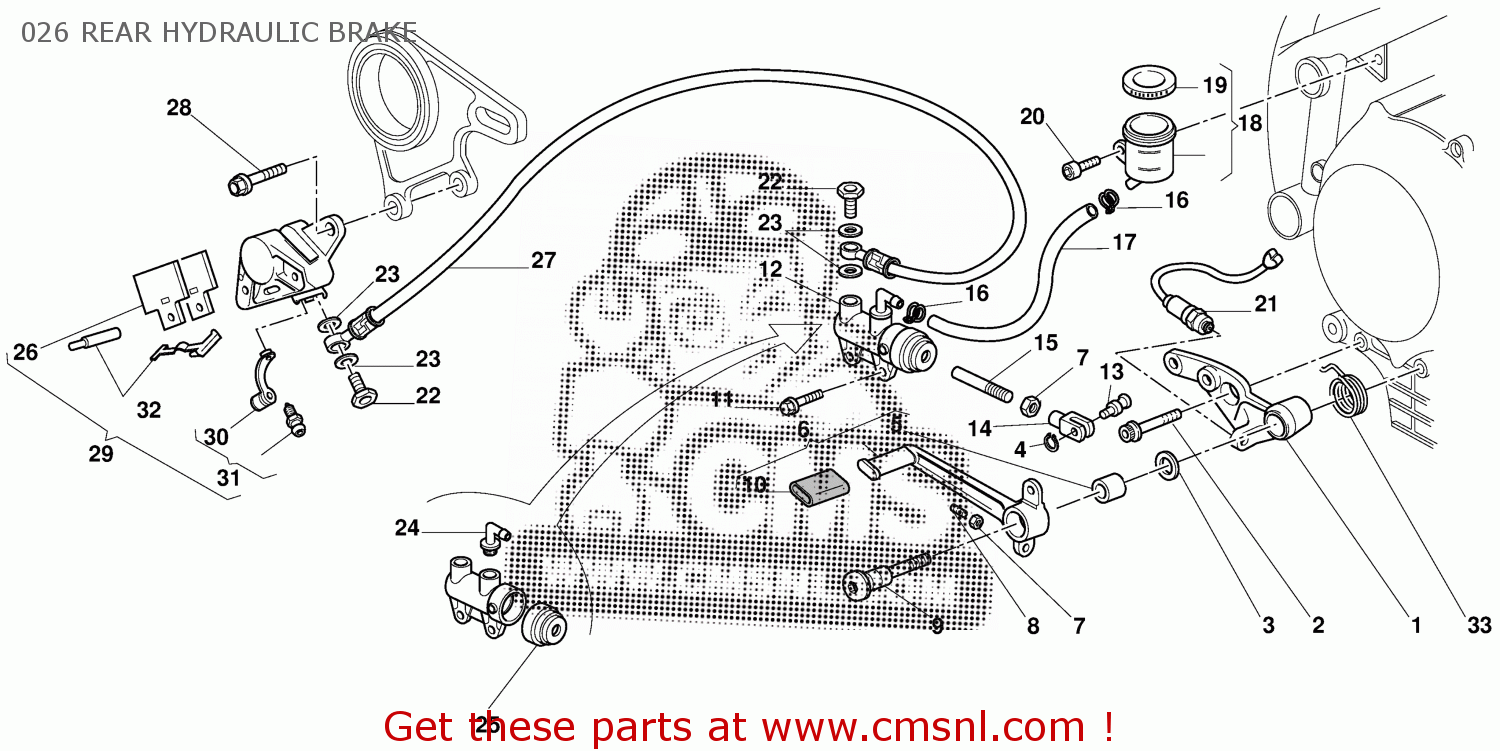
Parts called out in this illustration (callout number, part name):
1	BRACKET, REAR MASTER CYLINDER
2	SCREW TCEIF M10X1.5X25
3	WASHER 10.2X20X1
4	CIRCLIP
5	BUSH
6	PEDAL, BRAKE
7	NUT
8	THREADED DOWEL
9	PIN PEDAL
10	COVER PEDAL
11	BOLT 6X16
12	REAR BRAKE PUMP
13	PIN
14	YOKE
15	BRAKE CONTROL ROD
16	CLAMP
17	HOSE, OIL
18	RESERVOIR, BRAKE FLUID
19	CAP BRAKE FLUID TANK
20	BOLT.HEXAGON SOCKET HEAD M6X10
21	SWITCH, REAR BRAKE
22	SCREW, SPECIAL
23	COPPER GASKET 11.9X8.2X2
24	JOINT, HOSE
25	DUST COVER
26	REAR BRAKE PADS SET (NAS)
27	REAR BRAKE HOSE
28	SCREW
29	REAR BRAKE CALIPER
30	DUST PLUG
31	BREATHER VALVE
32	PAD PINS OVERHAUL KIT
33	SPRING
